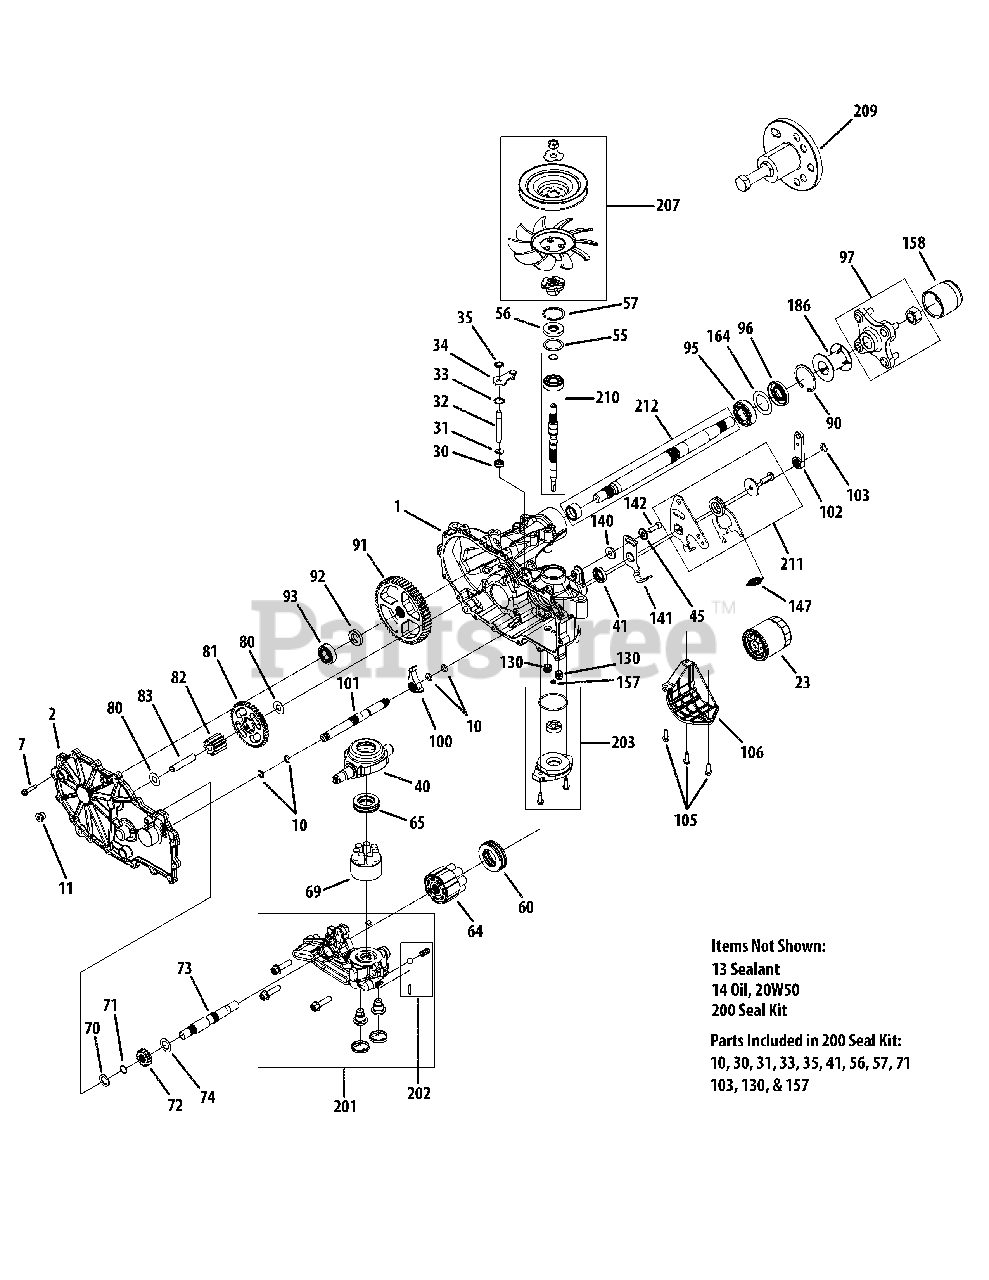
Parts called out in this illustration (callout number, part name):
1	Kit, Main Housing, LH Charge
2	Kit, Side Cover LH
7	Screw, Hex Washer
23	Filter, Spin-On 2.6 x 3.0
30	Seal, Lip, .375 x .75 x .25
31	Ring, Retaining .375 External
32	Rod, Bypass
33	Ring Retaining .750 Internal
34	Arm, Bypass
35	Ring, Ret .375 External
40	Trunnion, Swashplate
41	Seal, Lip 18 x 32 x 7
45	Washer, .34 x .88 x .06
55	Washer, 1.23 x 1.57 x .04
56	Seal, Lip 17 x 40 x 7
57	Ring Retaining Internal
60	Bearing, Thrust 35 x 62 x 18
64	Kit, 16cc Cylinder Block Assembly
65	Thrust Bearing, 30 x 52 x 13
69	Kit, Block, 7 Piston
70	Washer, .63 x 1.00 x .05
71	Ring, Reatining, Motor Shaft
72	Gear, 14T (Steel)
73	Shaft, Motor
74	Washer, .71 x 1.16 x .04
81	Gear, 45T
82	Gear, 11T (Steel)
83	Pin, Jackshaft
90	Ring, Retaining 2.25 Internal
91	Gear, 54T
92	Spacer, .750 x 1.00 x .257
93	Bearing, Ball 3/4 x 40mm x 12mm
95	Bearing, Ball 25.4 x 52 x 15
96	Seal, Lip, 1.0 x 2.06 x .38
97	Kit, Hub 4-Bolt
100	Pawl, Brake
101	Kit, brake Shaft
102	Handle, Actuating
103	Ring, Retaining, External .438
105	Screw, Hex Washer 1/4-20 x .75
106	Guard, Filter, LH
111	Kit, Fitting 1/2 Beaded 9/16 SAE
130	Tube, Charge Triple O-Ring
140	Spacer, .320 x 1.005 x .150
141	Arm, Return Left
142	SHCS, 5/16-24 x 7/8 (W/Patch)
147	Spring, Extension
157	Seal, Gerotor .281 x .420 x .160
158	Cap, Axle
164	Spacer, 1.355 x 2.035 x .021
186	Tube, Axle 2.03
200	Kit. Seal, ZT-2800
201	Kit, Center Section LH Charge
202	Kit, Charge Relief
203	Kit, Charge
207	Kit, Fan Pulley
207	Fan Only
207	Pulley Hub
209	Kit, Hub Puller
210	Kit, Input Shaft
211	Kit, RTN Bidirectional
212	Kit, Shaft Axle
